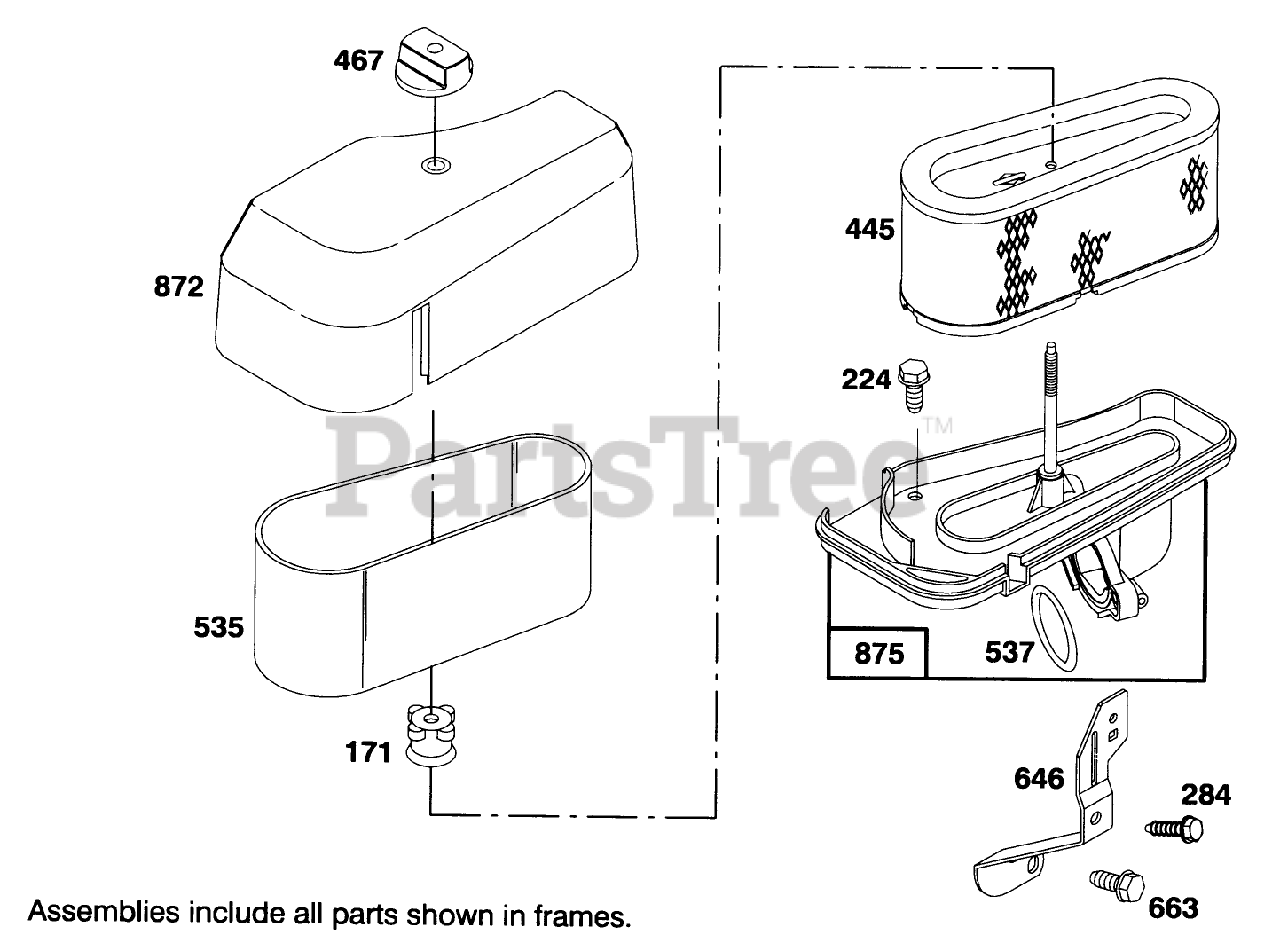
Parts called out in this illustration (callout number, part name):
224	Screw-Sem
284	Screw
445	Filter-Air
535	Filter-Air
537	O-Ring
646	Brace-Air Cleaner
663	Screw
872	Cover-Air Cleaner
875	Base-Air Cleaner
